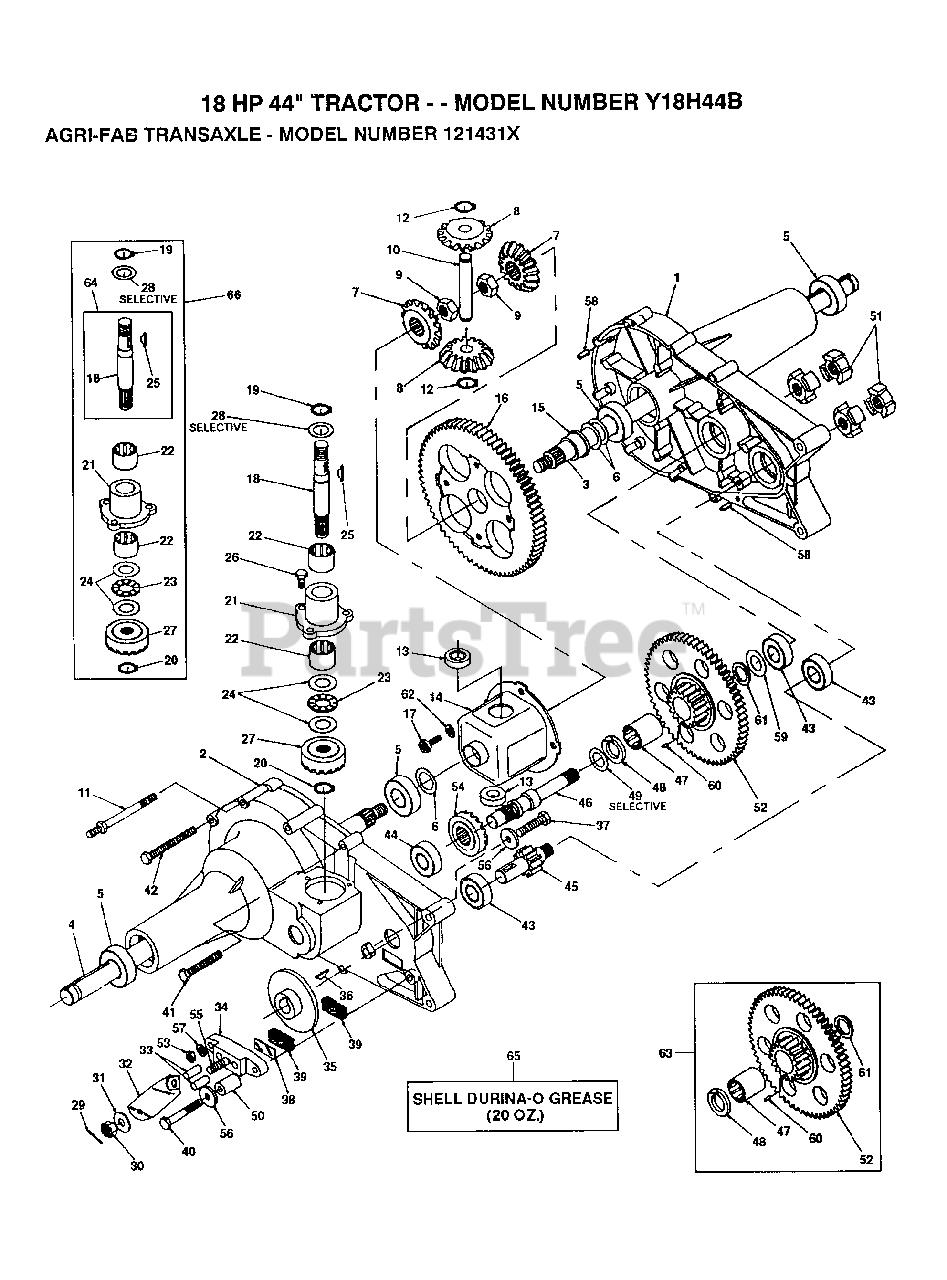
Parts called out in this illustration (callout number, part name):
1	HSG HALF LH-44077
2	HSG HALF RH-44076
3	AXLE LH -44273
4	AXLE RH-44272
5	BEARING.44121.AGR
6	WASHER -44008
7	GEAR MITER -44096
8	GEAR MITER -44097
9	NUT -44133
10	SHAFT CROSS
11	SCREW-STUD -44271
12	SNAP RING -44146
13	"THRUST, BEARING -44128"
14	HOUSING.ASM.DIFF.-62590
15	"FLANGE, BEARING-44129"
16	GEAR
17	BOLT -44126
18	SHAFT INPUT-44270
19	SNAP RING -44145
20	RET RING (44144)
22	"NEEDLE, BEARING 44099"
23	BEARING.NEE.44139
24	WASHER-44109
25	KEY.44136.HYDRO
26	SCREW
28	WASHER -44371
29	PIN COTTER -44101
30	WASHER -44150
31	WASHER FLAT -44130
32	ARM BRAKE 23710
33	PIN BRAKE ACTUATO -44127
34	BRAKE YOKE
35	DISC BRAKE -(44090)
36	KEY -44143
37	SCREW -44277
38	PLATE PUCK -44134
40	SCREW -44300
41	SCREW -44123
42	SCREW -44124
44	"BALL, BEARING -44232"
45	SHAFT PINION 44083
46	SHAFT DRIVE-44080
47	NEEDLE BEARING -44342
48	THRUST.BRONZE -44343
49	WASHER -44371
50	SPACER -23711
51	COUPLING- 44084
52	GEAR.60/17.44523
53	NUT -43178
54	PINION-DR.44079
55	BOLT SQ HD
56	WASHER -44278
57	WASHER -44137
58	PIN ROLL-44269
59	WASHER -44125
60	DOWEL PIN -44346
61	SEAL GREASE -44394
62	WASHER.43177.AGRI
63	ASS'Y GEAR REDUCT
65	GREASE.50416.10OZ
66	"KIT, SHAFT 62636"
